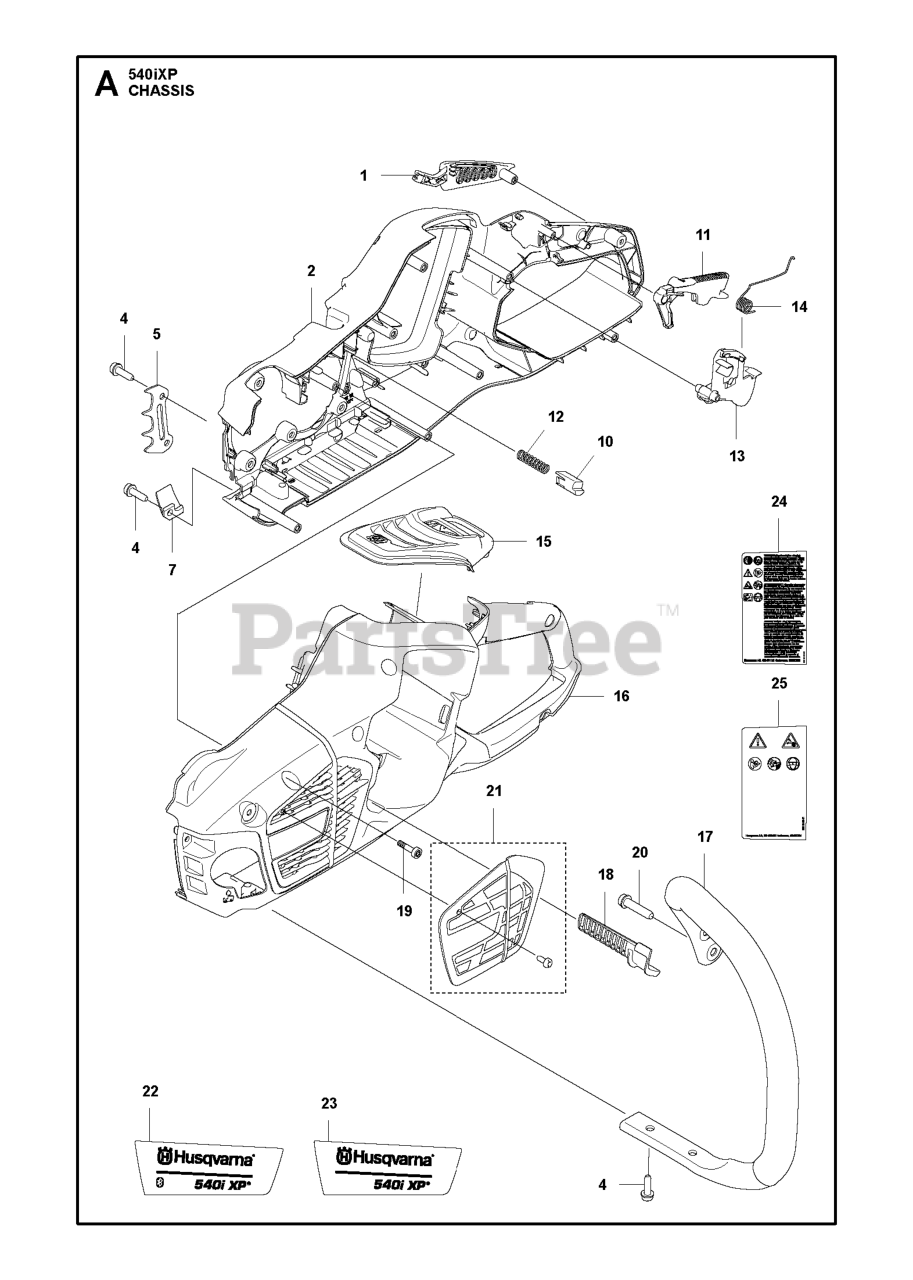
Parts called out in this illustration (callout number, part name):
2	CHASSIS
5	INDRE BARKSTØD
7	CHAIN CATCHER
10	PUSH BUTTON
12	SPRING PUSH OUT
15	Air Filter Cover
16	CHASSIS
17	FRONT HANDLE
17	Handles
18	Air Filters
19	SCREW ITXSCT PW4.2X18 10.9 ZN
21	Air Filter Cover
